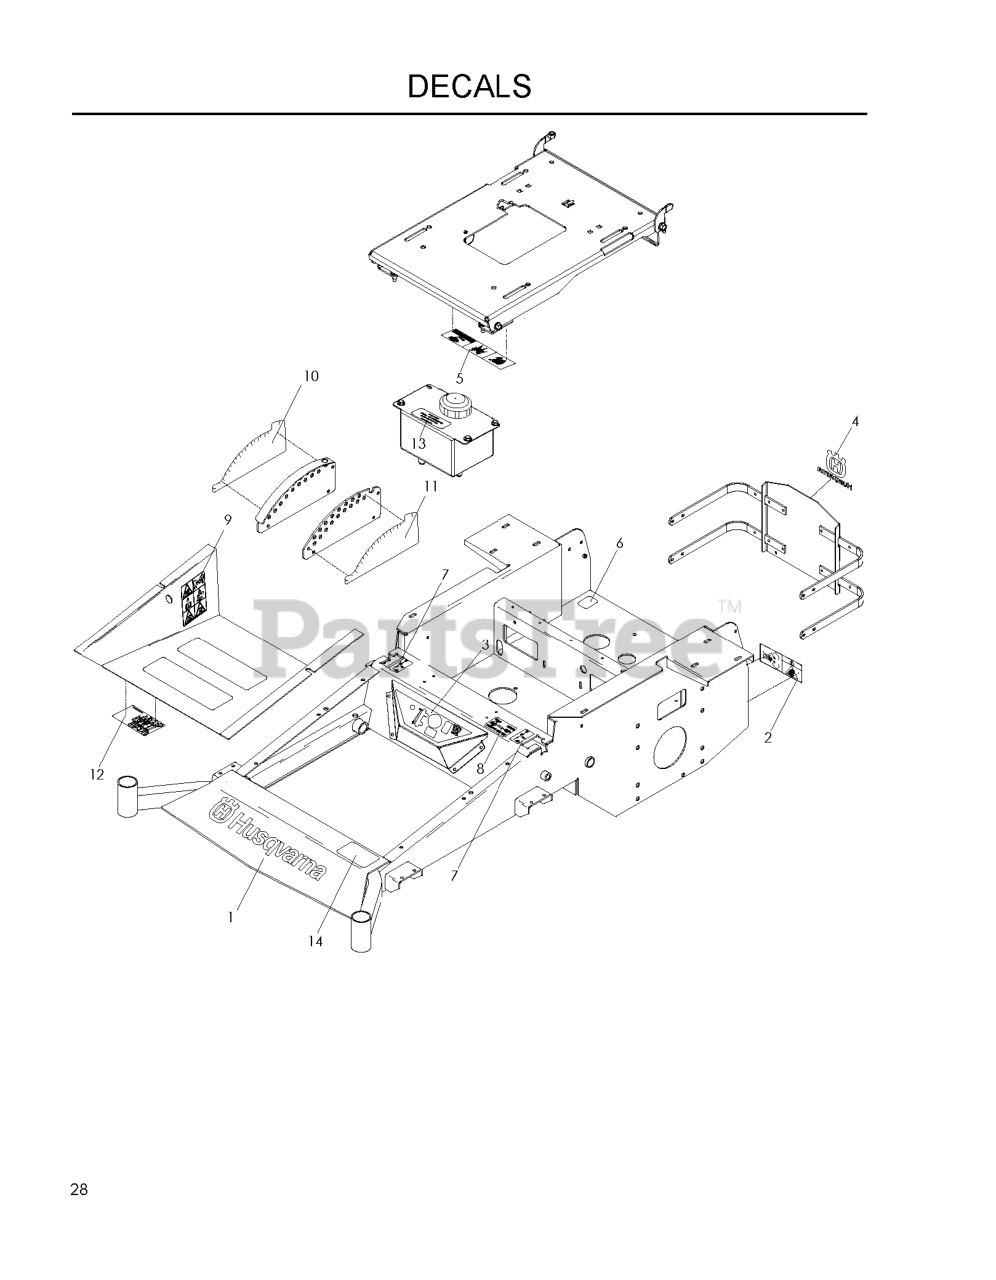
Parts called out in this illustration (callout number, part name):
1	DECAL, HUSQ 15" BLUE
2	DECAL, BELT DRIVE
3	DECAL, CONSOLE
4	DECAL, CROWN H 5-1/4 SILVER
5	EURO DECAL-BATTERY WARNIN6
6	DECAL, PROP. 65
7	DECAL, MOTION CONTROL
8	DECAL, F.S.T.
9	DECAL, WARNING
10	DECAL, HEIGHT
11	DECAL, HEIGHT
12	DECAL, SERVICE
13	DECAL, OIL TANK
14	DECAL, LZ25
